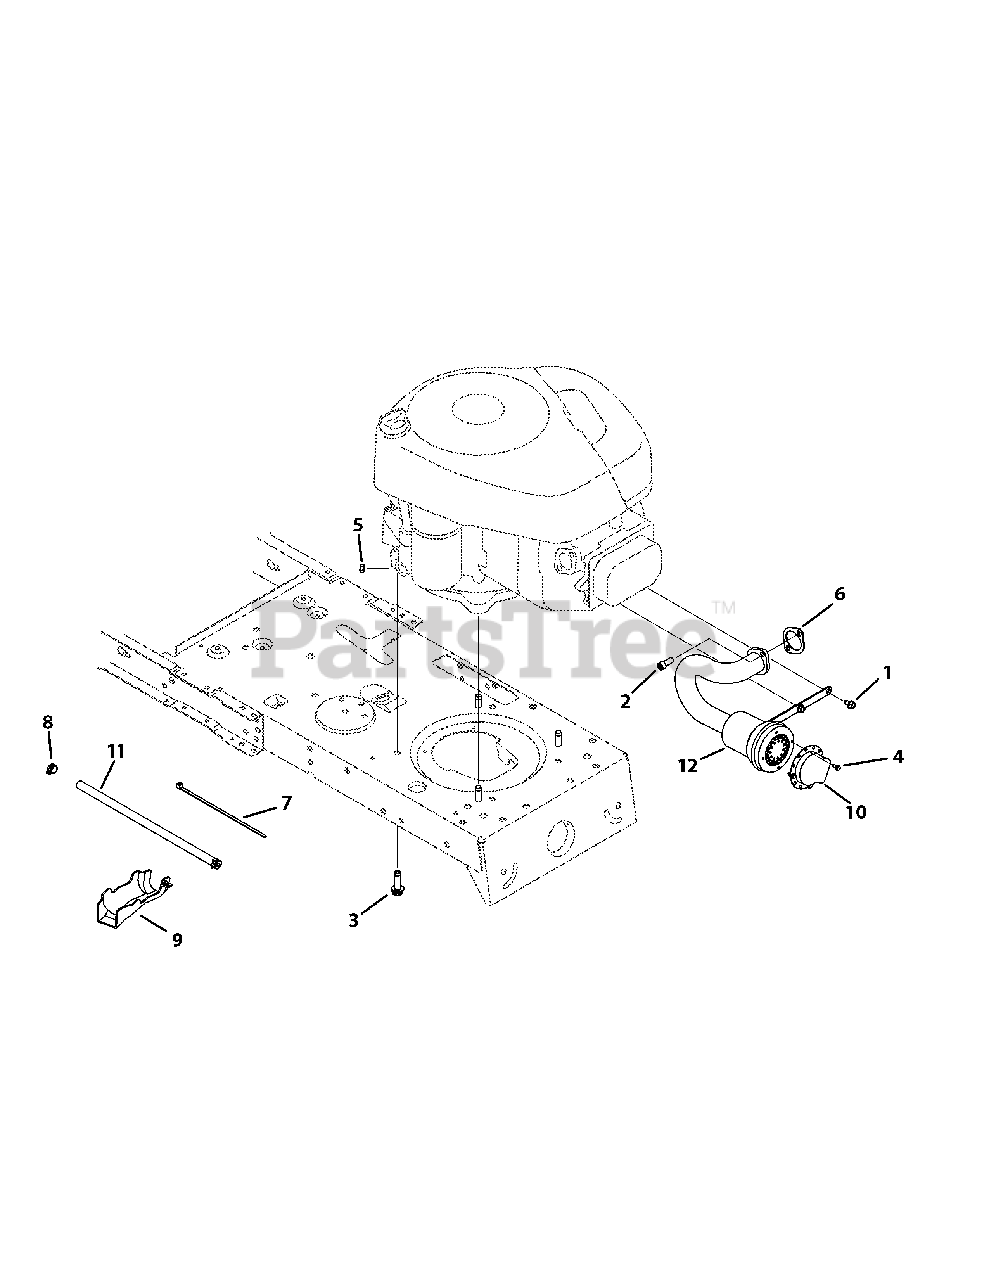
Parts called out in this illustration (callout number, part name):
1	Hex Wash S-Tapp Scr 1/4-20 x .50
2	Socket HD Cap Scr. 5/16-18 x .75
3	Hex Wash S-Tapp Scr 3/8-16 x 1.0
4	Hex Wash HD AB S-Tapp Scr #8-.50
5	Sems Nut 1/4-20
6	Exhaust Gasket
7	Cable Tie
8	Hose Clamp
9	Oil Drain Sleeve
10	Muffler Deflector
11	Fuel Line
12	Muffler, Bug
